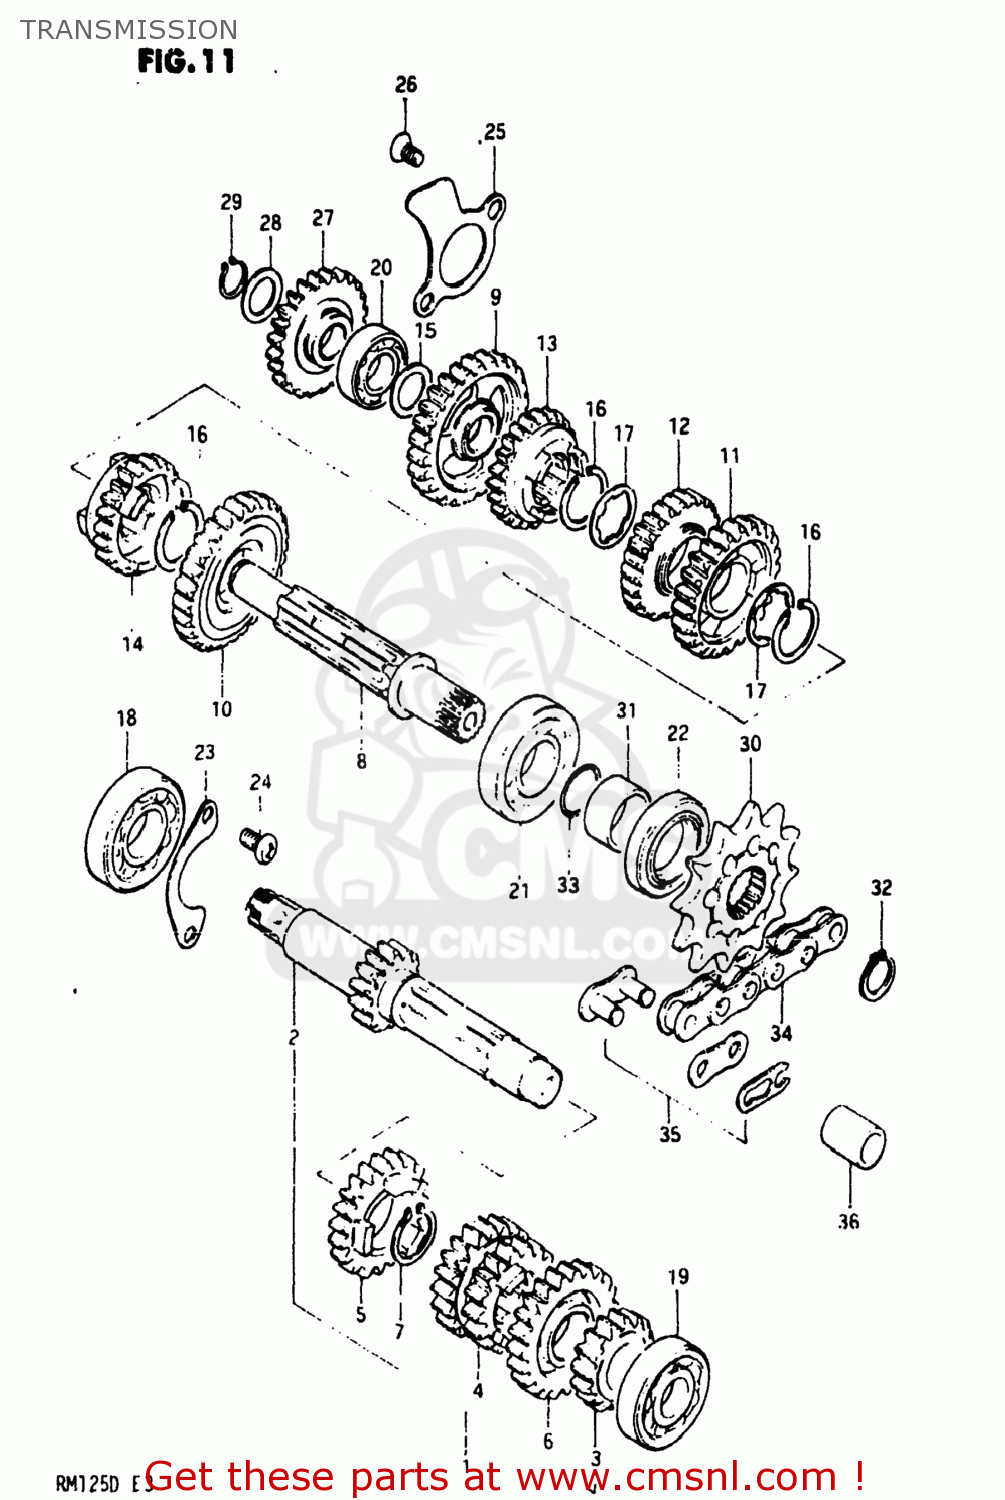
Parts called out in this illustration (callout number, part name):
0	SPROCKET,ENGINE
1	SHAFT,COUNTER
2	SHAFT,COUNTER
3	GEAR,SECOND DRIVE
4	GEAR,THIRD/FOURTH DRIVE
5	GEAR,FIFTH DRIVE
6	GEAR,SIXTH DRIVE
7	CIRCLIP
8	SHAFT,DRIVE
9	GEAR,FIRST DRIVEN
10	GEAR,SECOND DRIVEN
11	GEAR,THIRD DRIVEN
12	GEAR,FOURTH DRIVEN
13	GEAR,FIFTH DRIVEN
14	GEAR,SIXTH DRIVEN
15	WASHER,THRUST
16	CIRCLIP
17	WASHER,LOCK
18	Bearing
19	BEARING
20	BEARING, RH
21	BEARING(20X47X14)
22	SEAL,OIL(25X40X7)
23	RETAINER,CNTR SHAFT BEARING
24	SCREW 6X12
25	RETAINER,DRIVESHAFT
26	SCREW
27	GEAR,KICK STARTER IDLE
28	WASHER,THRUST
29	CIRCLIP,15MM
30	SPROCKET,ENGINE
31	SPACER(20X25X12.5)
32	CIRCLIP
33	O RING(D:1,ID:19.5)
34	CHAIN ASSEMBLY,DRIVE
35	JOINT ASSEMBLY,CHAIN
36	CUSHION
